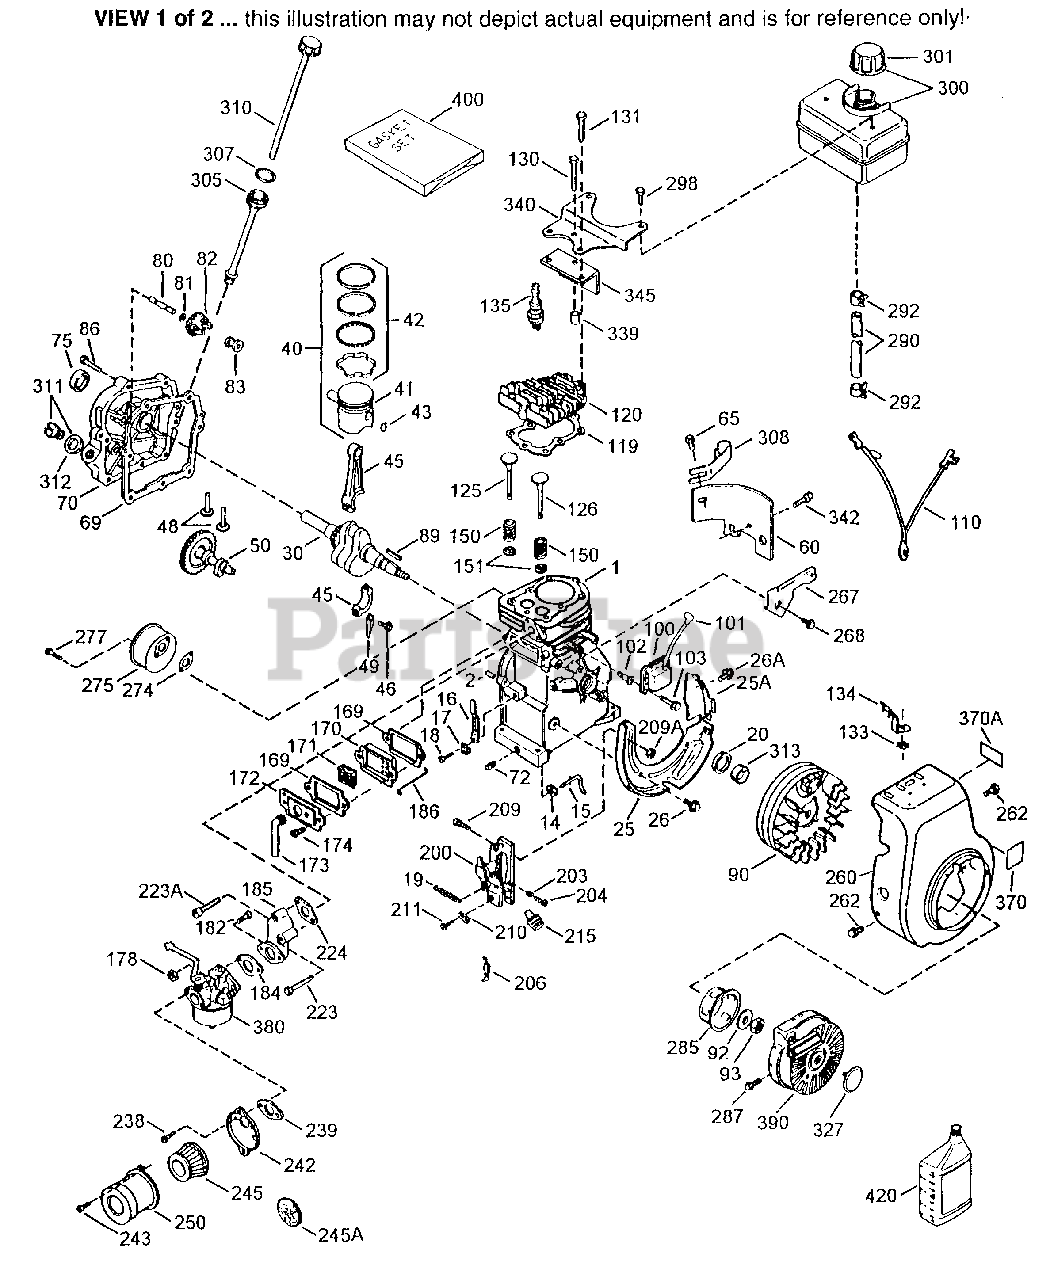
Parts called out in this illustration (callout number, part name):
1	"Cylinder (Incl. 2, 20, 72 & 125)
2	Dowel Pin
14	Flat Washer
15	Governor Rod
16	Governor Lever
17	Governor Lever Clamp
18	Screw, T-15, 8-32 X 19/64"
19	Extension Spring
20	Oil Seal
25A	Baffle Extension
30	Crankshaft (Incl. 75)
40	Piston, Pin & Ring Set (Std.) (Incl. 41, 42 & 43)
40	Piston, Pin & Ring Set (.010" OS) (In cl. 41, 42 & 43)
42	Ring Set (Std.)
42	Ring Set (.010" OS)
43	Piston Pin Retaining Ring
45	Connecting Rod Assembly (Incl. 46 & 4 9)
46	Connecting Rod Bolt
48	Valve Lifter
49	Oil Dipper
50	Camshaft (BCR)
60	Blower Housing Extension
65	Screw, 10-24 X 9/16"
69	Cylinder Cover Gasket
70	Cylinder Cover (Incl. 75 Thru 83 & 31 1)
72	Oil Drain Plug (Sq. Hd., 1/4-18)
75	Oil Seal
80	Governor Shaft
81	Flat Washer
82	Governor Gear Assembly (Incl. 81)
86	Screw, 1/4-20 X 1-1/4"
89	Flywheel Key
90	Flywheel
92	Belleville Washer
93	Flywheel Nut
100	Solid State Ignition
101	Spark Plug Cover
102	Solid State Mounting Stud
103	Screw, T-15, 10-24 X 15/16"
110	Ground Wire
119	Cylinder Head Gasket
120	Cylinder Head (Incl. 130A)
125	Exhaust Valve (Std.) (Incl. 151)
125	Exhaust Valve (1/32" OS) (Incl. 151)
126	Intake Valve (Std.) (Incl. 151)
126	Intake Valve (1/32" OS) (Incl. 151)
130	Screw, 5/16-18 X 1-7/16"
130	Screw, 5/16-18 X 2"
130B	Screw, 1/4-20 X 1/2"
135	Resistor Spark Plug (Rj17Lm)
150	Valve Spring
151	Valve Spring Cap
169	Valve Cover Gasket
170	Breather Body
171	Breather Element
172	Valve Cover
174	Screw, 10-24 X 1/2"
178	Nut & Lock Washer 1/4-28
181	Screw, 1/4-28 X 1-11/16"
182	Screw, 1/4-28 X 7/8"
184	Carburetor To Intake Pipe Gasket
185	Intake Pipe
186	Governor Link
200	Control Bracket (Manual/Remote Conver tible) (Incl. 203 Thru 209A
203	Compression Spring
204	Screw, T-10, 5-40 X 7/16"
206	Terminal - Shorting On-Off
212	Speed Control Lever Bushing
212A	Bearing Plate
215	Speed Control Knob
216	R.P.M. Adjusting Lever
217	Speed Control Lever
222	Screw, 10-32 X 1/2"
223	Screw, 1/4-20 X 1-19/32"
223A	Screw, 1/4-20 X 1-3/8"
224	Intake Pipe Gasket
238	Screw, 8-32 X 3/8"
239	Air Cleaner Gasket
242	Air Cleaner Base
245	Air Filter (Paper)
250	Air Cleaner Cover
260	Blower Housing
264A	Screw, 1/4-20 X 5/8"
267	Hold Down Bracket
285	Starter Cup
287	Screw, 8-32 X 21/64"
290	Fuel Line (8.62")
290	Fuel Line (16")
292	Fuel Line Clamp
295	Fuel Shut-Off Valve (Incl. 292)
298	Screw, 1/4-15 X 3/4"
300	Fuel Tank (Incl. 292 & 301) (2 Quart)
301	Fuel Cap (Black)
305	Oil Fill Tube
310	Dipstick
311	Oil Fill Plug (Incl. 312)
312	Oil Fill Plug Gasket
340	Fuel Tank Bracket
342	Screw, 1/4-20 X 7/16"
345	Heat Baffle
355	Starter Handle (Mitten Grip)
370	Decal - Important Lubrication - Sae 3
370	Speed Control Decal
370	Decal - Tecumseh Logo For Top Of Reco il Starter
380	Carburetor (Incl. 184)
390	Rewind Starter
400	* Gasket Set (Incl. Items Marked *)
420	Sae 30 4-Cycle Engine Oil (Quart) (Su mmer)
